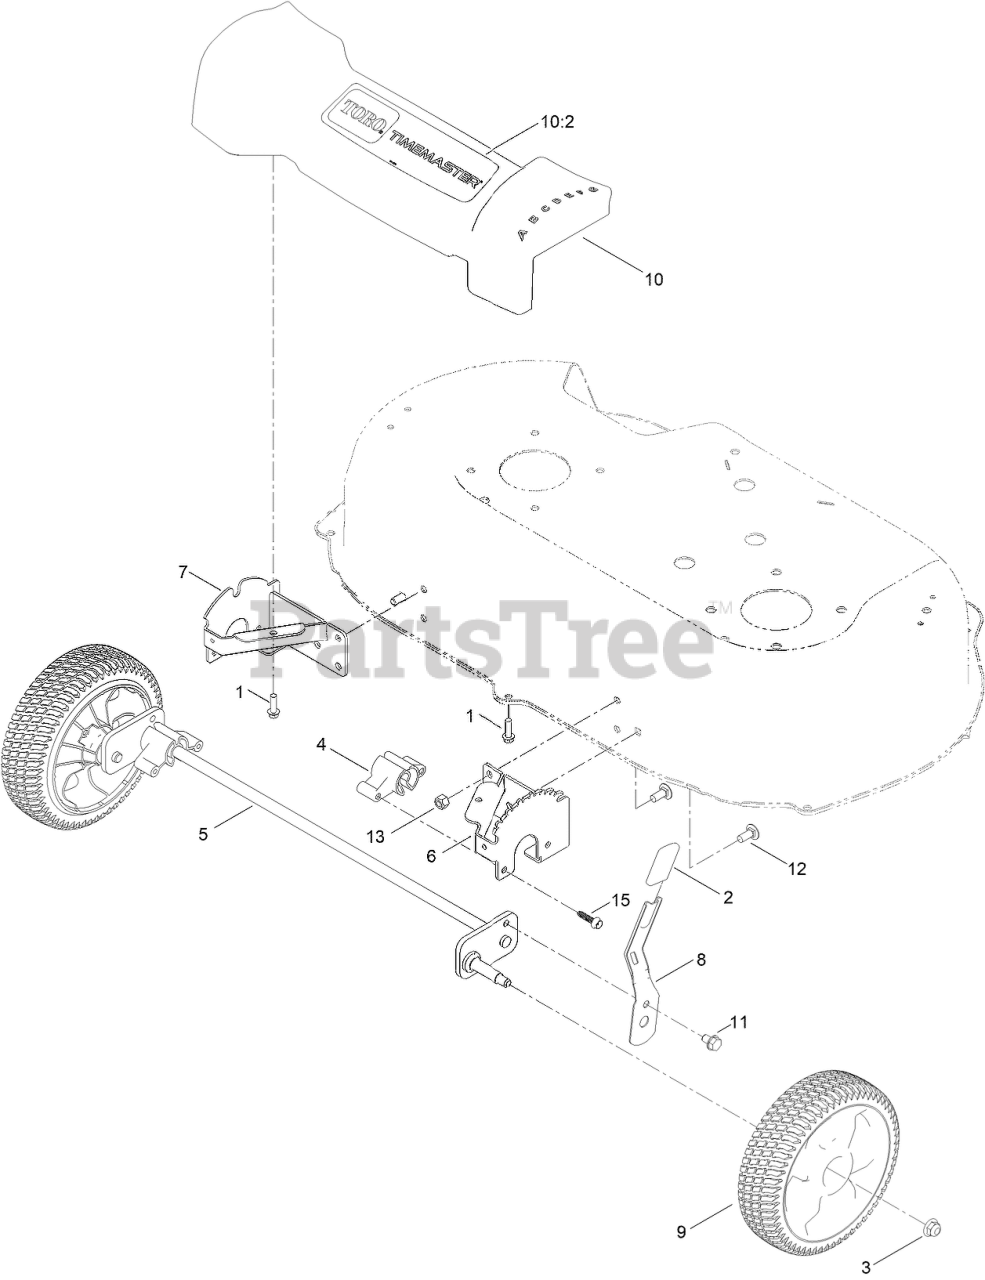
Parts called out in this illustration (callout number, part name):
1	SCREW-HWH
2	GRIP-LEVER
3	NUT-HF, NI
4	BUSHING-PIVOT, FRONT
5	FRONT AXLE ASM
6	PLATE-HOC, LH
7	PLATE-HOC, RH
8	ARM-SPRING
9	8 INCH WHEEL ASM
10	FRONT COVER ASM
10:2	DECAL-COVER, FRONT
11	SCREW-HWH
12	SCREW-CARR
13	NUT-LOCK, NI
15	SCREW-FLANGE, PLASTIC
